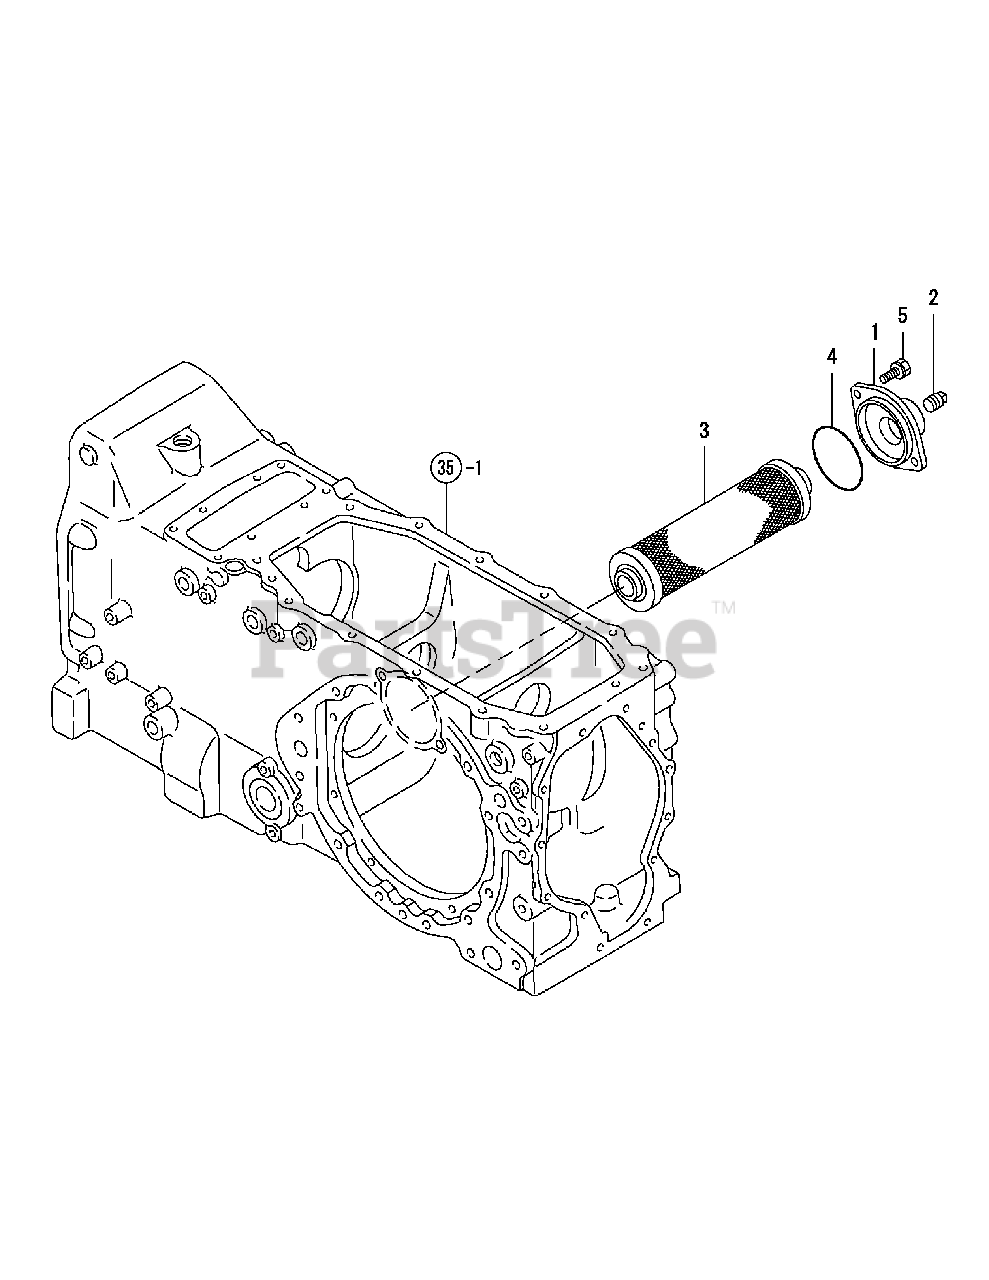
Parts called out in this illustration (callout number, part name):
1	COVER, STRAINER
4	O-RING 1A G-65.0
5	BOLT W/WASHER M8X20
